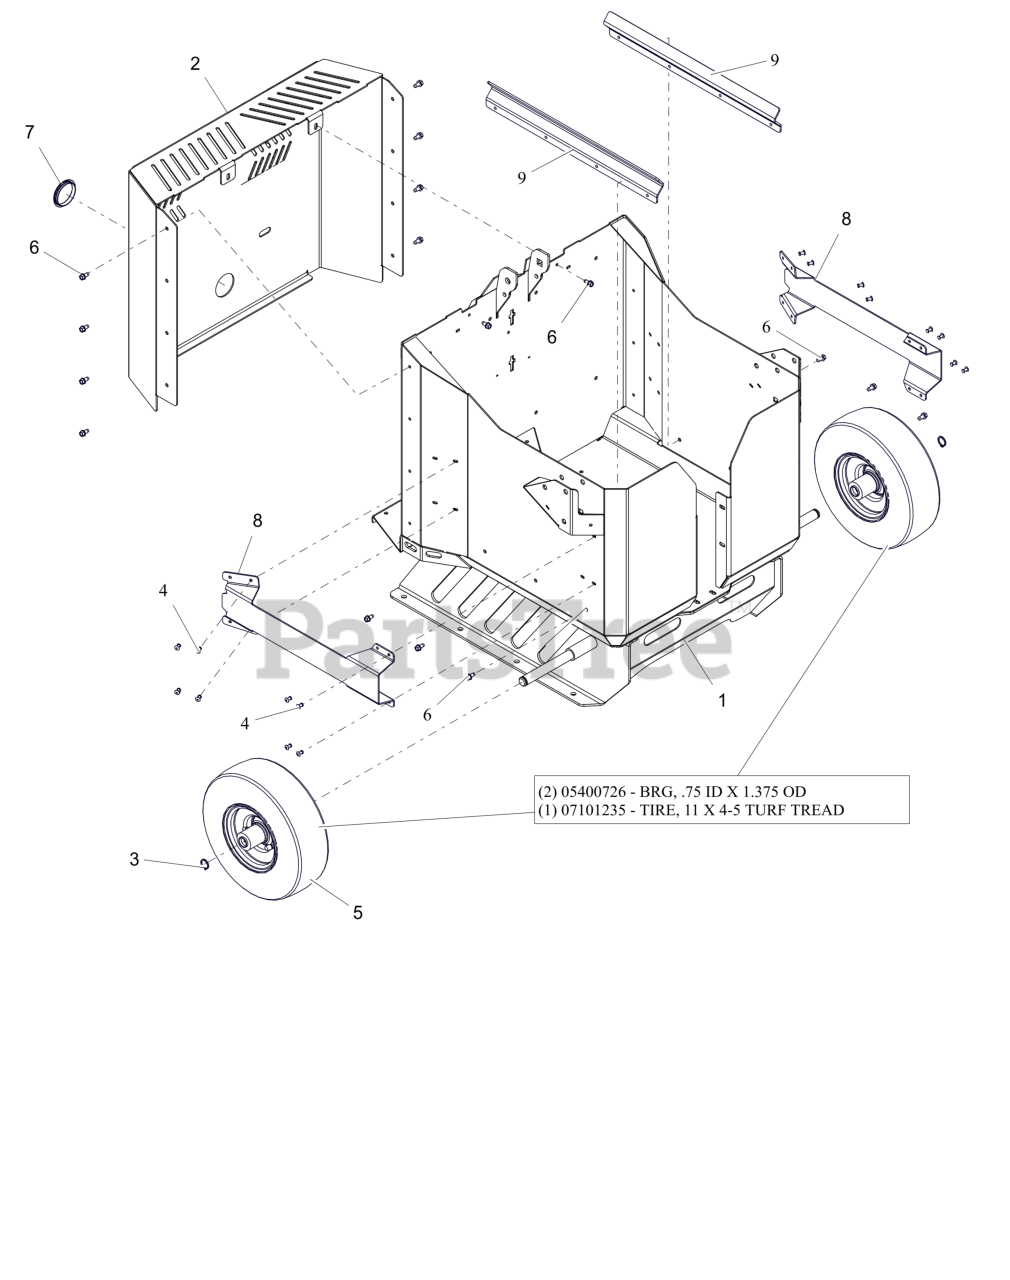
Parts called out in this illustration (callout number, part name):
1	WLDMT, BATTERY FRAME (BLACK)
2	WLDMT, REAR PANEL (BLACK)
3	RG-RTNG-EXT .689X.078
4	RVT-POP.187X.527 DOME ST
5	ASM, WHL/TIRE 11X4.00-5
5	TIRE, 11X4-5 TURF TREAD
5	BRG, .75 ID X 1.375 OD
6	SCR-TAP .25-20X.50 HWH ZCC
7	GROMMET, RUBBER 1.89 ID
8	PLATE, VINYL BRANDING (BLUE)
9	DEFLECTOR, OBC BATTERY (BLACK)
